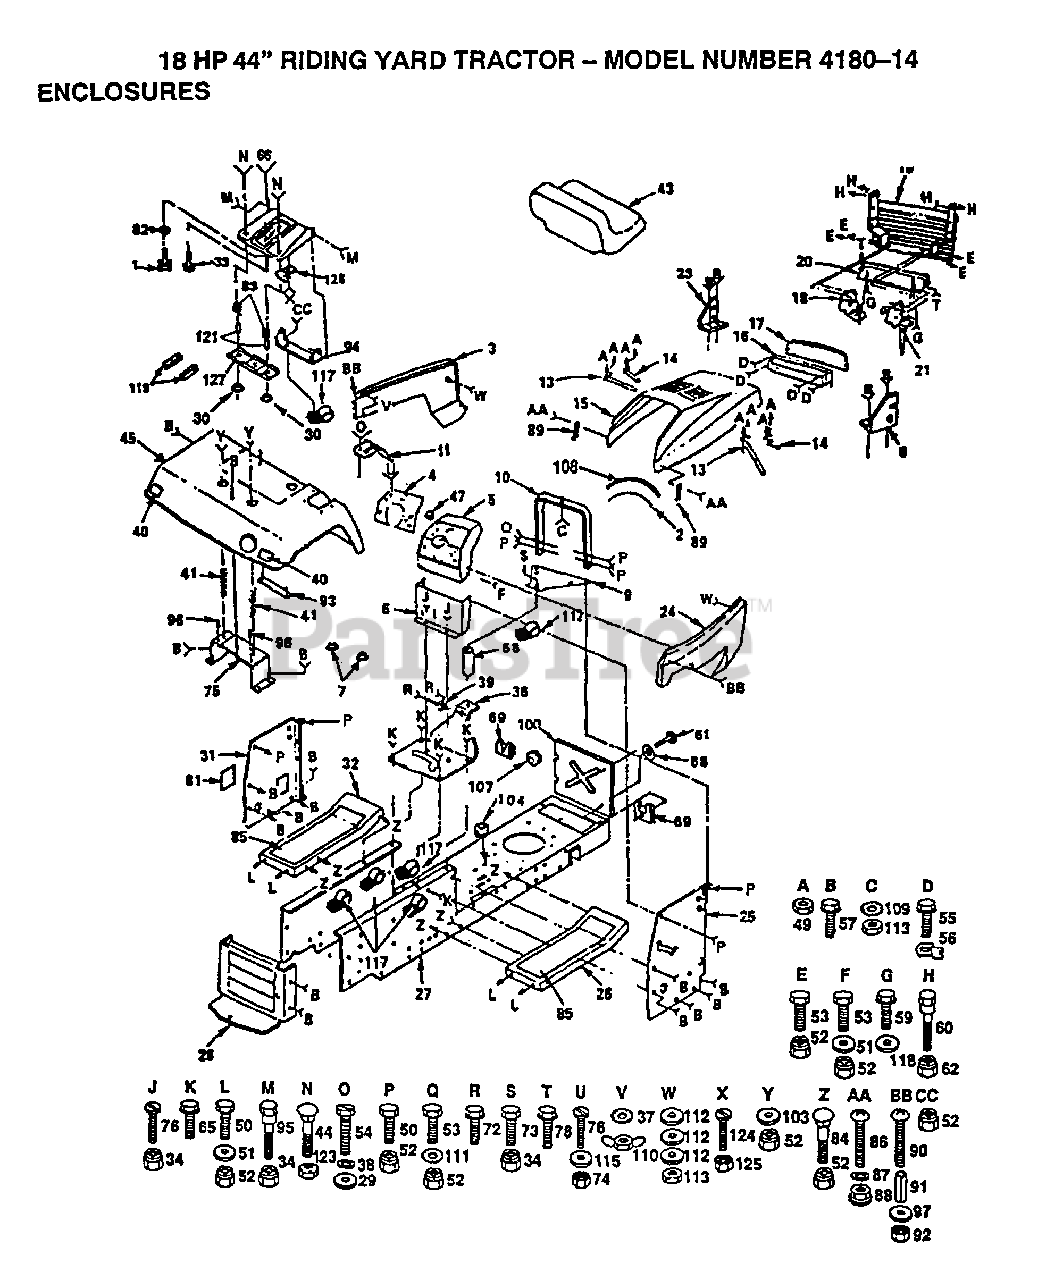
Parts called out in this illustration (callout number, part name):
1	"KNOB 1/2"" YT"
2	FOAM STRIP T
6	LOWER DASH
7	CAP SPRING
8	SUPPORT RH YTH
11	CONSOLE SHIFTER
17	LENS LT
18	SUPPORT LH YTH
21	SUPPORT RH YTH
23	SUPPORT LH YTH
27	CHASSIS
28	DRAW BAR
29	WASHER
30	BUSHING
31	PANEL DASH LH
33	"BOLT,SHOULDER"
37	LOCKWASHER GT
38	"WASHER,LOCK"
40	REFLECTOR-TAIL YT
41	SPRING COMPRESSIO
44	BOLT
45	FENDER
47	PLUG BUTTON T
49	NUT
51	WASHER
53	BOLT
54	SCREW
56	"""J"" FASTENER LT"
57	SCREW
58	SPACER
59	SCREW
61	STUD.1/4.TURN
63	SPRING COMPRESSED
65	SCREW LT
68	RETAINER LT
69	RECEPTACLE LT
73	BOLT
76	SCREW
78	SCREW
81	COVER ACCESS
82	WASHER
84	BOLT
85	"PAD,FOOTREST"
86	SCREW
87	LOCKWASHER
88	WELDNUT
89	HOOD LATCH T
90	SCREW
91	SPACER LT
96	NUT-PUSH YT
97	WASHER
103	WASHER
104	SNAP BUSHING T
108	STRIP - FOAM
111	LOCKWASHER
112	WASHER PM
115	WASHER
117	CLIP T
118	WASHER
119	STRIP FORM
121	SPACER SPLIT
125	"NUT,KEPS"
127	BRKT SWITCH
